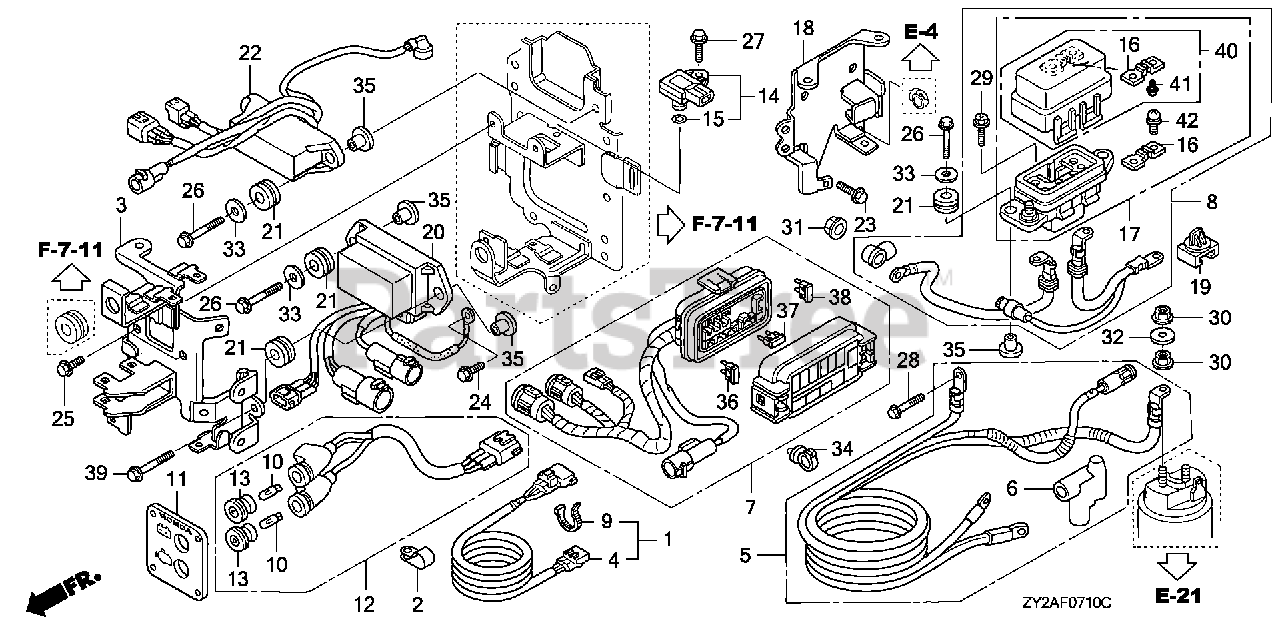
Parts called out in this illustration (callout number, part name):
1	CORD KIT, INDICATOR (3P/6P) (ANALOG)
2	CLAMP F, CABLE
3	BRACKET, CONNECTOR A
4	WIRE ASSY., INDICATOR (3P/6P) (ANALOG)
5	CABLE ASSY., STARTER
6	COVER, STARTER TERMINAL
7	CABLE ASSY., MAIN FUSE
8	CABLE ASSY., ALTERNATOR FUSE
9	TIE, CABLE (2.4X92) (NATURAL)
10	BULB, WEDGE BASE (T6.5) (12V 3W)
11	PANEL, INDICATOR (2-BULB)
12	LAMP ASSY., INDICATION (2-BULB)
13	LENS, SPEEDOMETER PILOT
14	SENSOR ASSY., MAP
16	FUSE (150A)
17	BOX ASSY., FUSE (150A)
18	BRACKET, FUSE BOX
19	CLIP, CONNECTOR HOLDER (B)
20	RELAY ASSY., POWER TILT
21	GROMMET, RELAY
22	RELAY ASSY., MAIN
23	BOLT, FLANGE (6X14) (CT200)
24	BOLT, FLANGE (6X12)
25	BOLT, FLANGE (6X10)
26	BOLT-WASHER (6X25)
26	BOLT, FLANGE (6X22)
27	BOLT-WASHER (5X18)
28	BOLT, FLANGE (8X18)
29	BOLT-WASHER (6X16)
30	NUT-WASHER (8MM)
31	NUT-WASHER (6MM)
32	WASHER, PLAIN (8MM)
33	WASHER, PLAIN (6MM)
34	CLIP, HARNESS
35	COLLAR, MODULE IGNITION CONTROL CASE (CDI)
36	FUSE, MINI (10A)
37	FUSE, MINI (15A)
38	FUSE, MINI (30A)
39	BOLT, FLANGE (6X22)
40	COVER ASSY., FUSE (150A)
41	SCREW-WASHER (3X7)
42	SCREW-WASHER (5X12)
